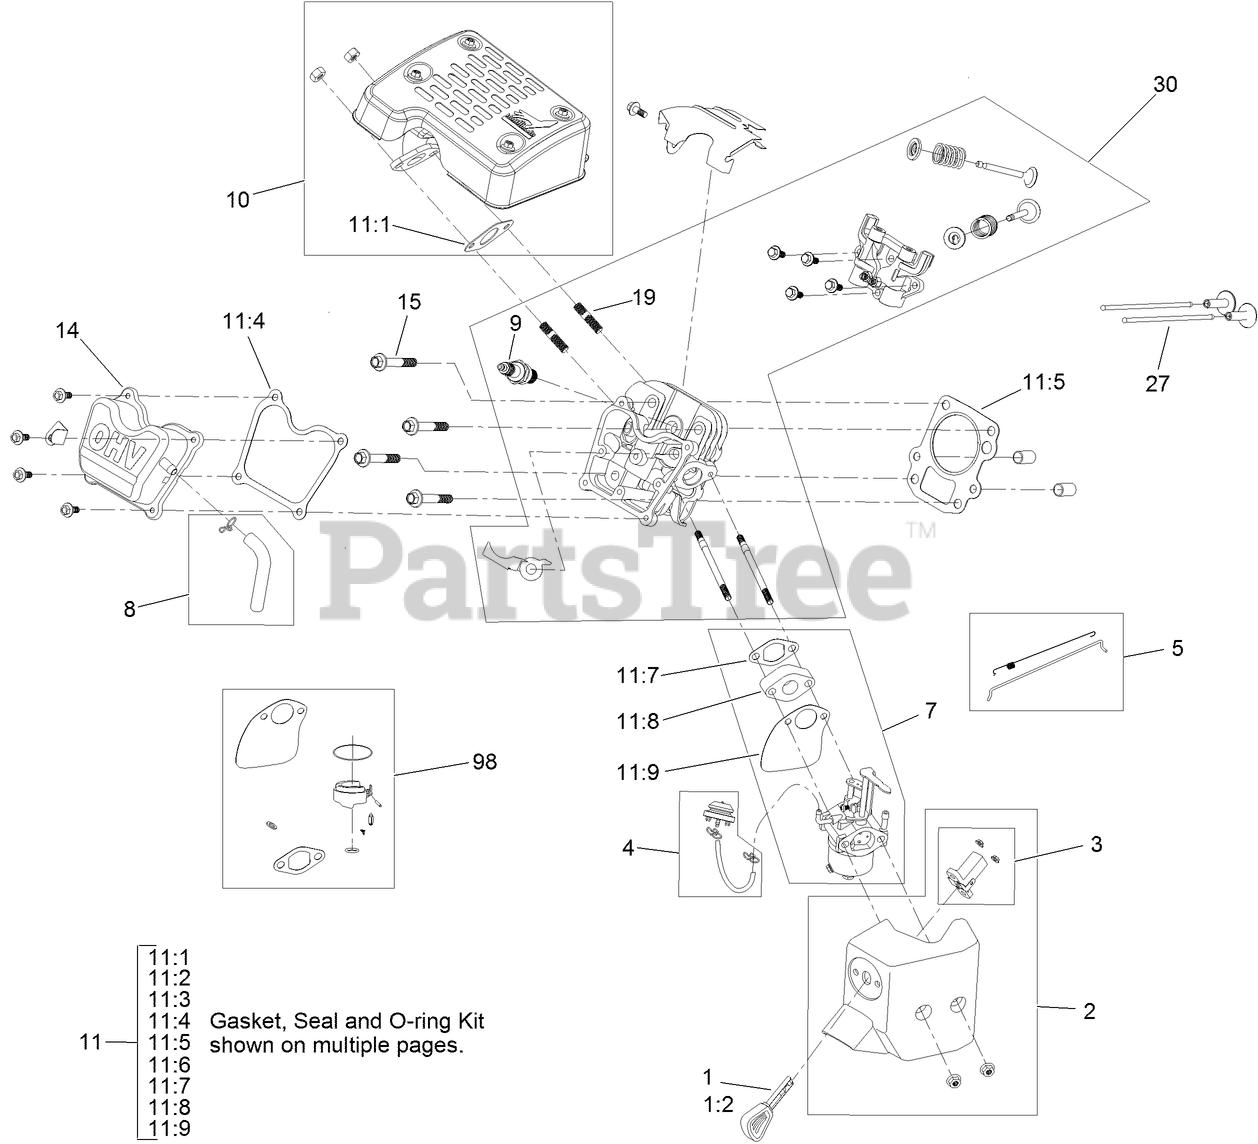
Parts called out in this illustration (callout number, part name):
1	KEY AND LANYARD KIT
2	HEATER BOX KIT
3	SWITCH KIT
4	PRIMER BULB KIT
5	GOVERNOR KIT
7	COMPLETE CARB SERVICE KIT
8	BREATHER TUBE KIT
9	SPARK PLUG
10	MUFFLER KIT
11	GASKET, SEAL AND O-RING KIT
11:1	GASKET-EXHAUST
11:2	SEAL-OIL
11:3	SEAL-OIL
11:4	GASKET-COVER, VALVE
11:5	GASKET-HEAD, CYLINDER
11:6	GASKET-COVER, CRANKCASE
11:7	GASKET-INSULATOR
11:8	INSULATOR-CARBURETOR
11:9	GASKET-CARBURETOR
14	VALVE COVER ASM
15	SCREW-HHF
19	STUD-EXHAUST
27	ROD-PUSH
30	COMPLETE HEAD ASM
98	CARBURETOR REPAIR KIT
